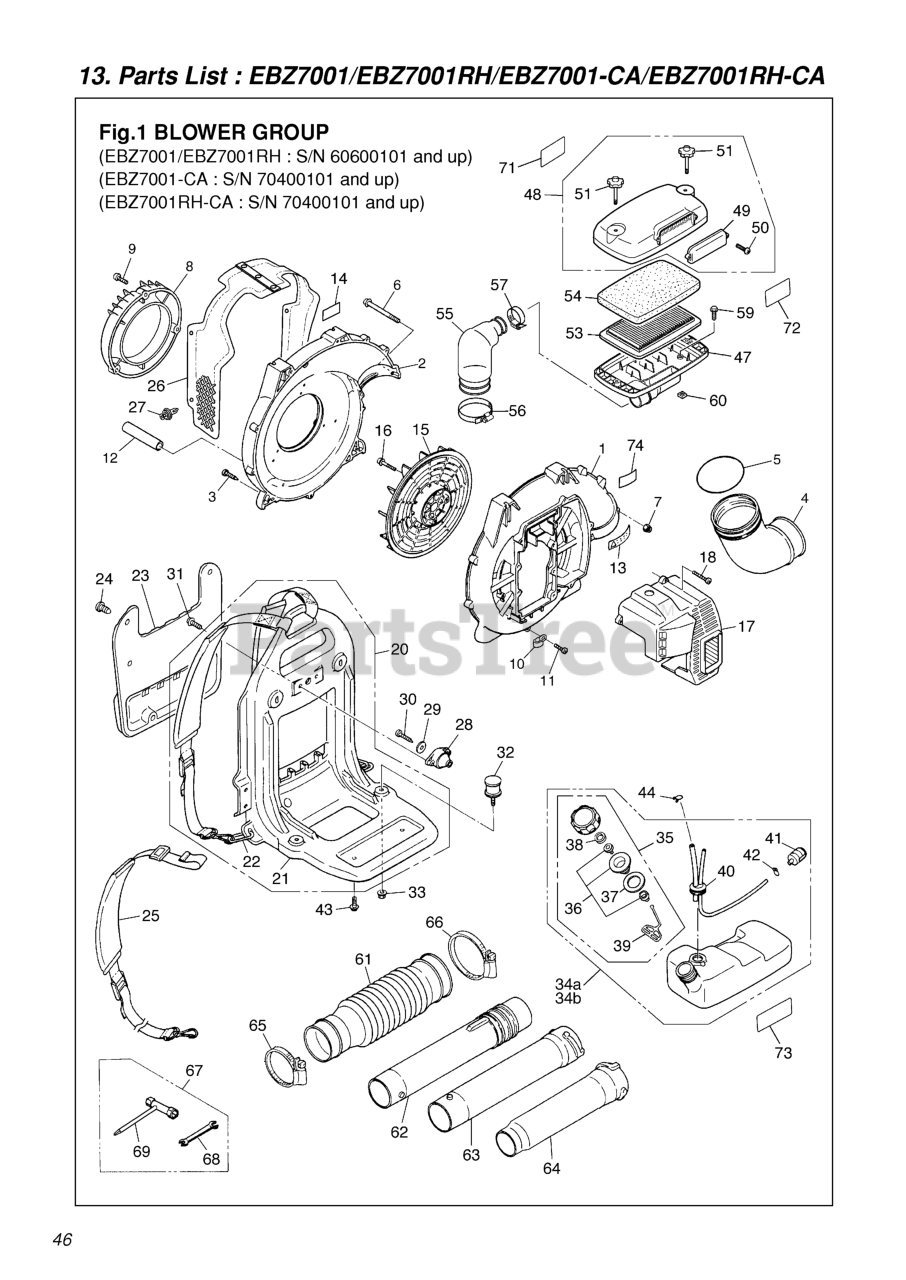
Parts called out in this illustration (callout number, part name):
1	VOLUTE CASE
2	VOLUTE COVER RPLS 848L5C55B3
3	SCREW
4	ELBOW
5	O-RING
6	SCREW TORX
7	NUT (B)
8	COVER, INLET
9	SCREW
10	CLAMP (RPLS 1140-72231)
12	TUBE (RPLS. 07270-01507)
13	LABEL, CAUTION (RPLS -31910)
14	LABEL, NET
15	FAN
16	BOLT
17	ENGINE COVER
18	SCREW
20	FRAME ASSY
21	FRAME COMP
22	RING (REPLACES -21120)
23	PAD
24	CLIP (RPLS 3490-21320)
25	BAND ASSY
26	NET COMP
27	CLIP
28	DAMPER, UPPER
29	WASHER
30	BOLT, TORX
31	SCREW TORX
32	DAMPER, LOWER
33	NUT, M6
34A	TANK ASSY (RPLS. -85100)
35	CAP ASSY
36	HOLDER (REPLACES -85230)
37	PACKING
38	FILTER
40	PIPE COMPLETE
41	FILTER ASSY
42	CLIP (REPLACES 2841-31280)
43	SCREW TORX
44	CLIP
47	BODY (RPLS. T4012-82111)
48	COVER ASSY
49	COVER
50	SCREW
51	KNOB BOLT (RPLS T4012-82800)
53	ELEMENT PAPER (RPLS T401282310)
54	ELEMENT (FOAM) (RPLS -82320)
55	HOSE
56	CLAMP
57	CLAMP
60	NUT
61	FLEX HOSE
62	SWIVEL JOINT
63	PIPE, STRAIGHT
64	PIPE, END
65	CLAMP
66	CLAMP
67	TOOL-SET
68	SPANNER, 8 x 10 (RP 090100810)
71	LABEL
72	LABEL, EBZ7001
73	LABEL
74	LABEL, SOUND
